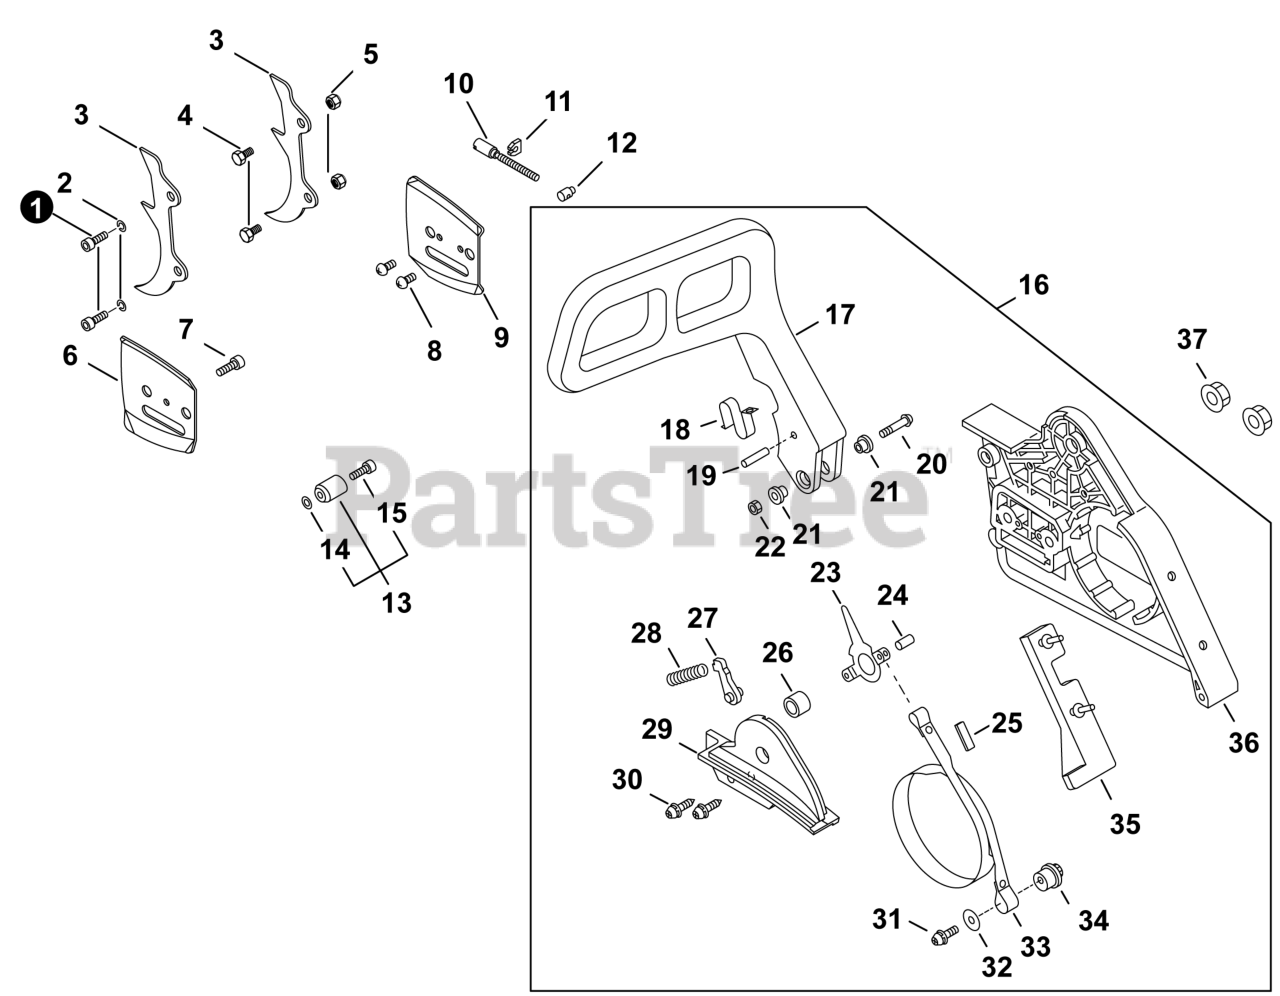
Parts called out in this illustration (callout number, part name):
1	BOLT 6×20
2	WASHER, SPRING 6
3	SPIKE, BUMPER
5	NUT, LOCK 6
6	PLATE, GUIDE - INNER
7	SCREW 4×8
8	SCREW 3×6
9	PLATE, GUIDE - OUTER
10	SCREW, ADJUSTER
12	TENSIONER, CHAIN
13	CHAIN CATCHER KIT
14	WASHER, FLAT 5.5×10×0.8
15	BOLT 5×20
16	BRAKE ASSY, CHAIN
17	LEVER, BRAKE
18	SPRING, FLAT
19	PIN 3.5×26
21	COLLAR 5.3×10×13×L5
22	NUT, LOCK M5
23	LEVER, BRAKE
24	PIN, SPRING 4×8.8
25	SEAL, BRAKE
26	WASHER 5.2×12×14
27	STOPPER, BRAKE
28	SPRING, BRAKE
29	COVER, BRAKE
30	SCREW 4×10
31	SCREW 5×25
33	BAND, BRAKE
34	ADJUSTER, BRAKE
36	GUARD, SPROCKET
37	NUT, FLANGE M8×1.25
